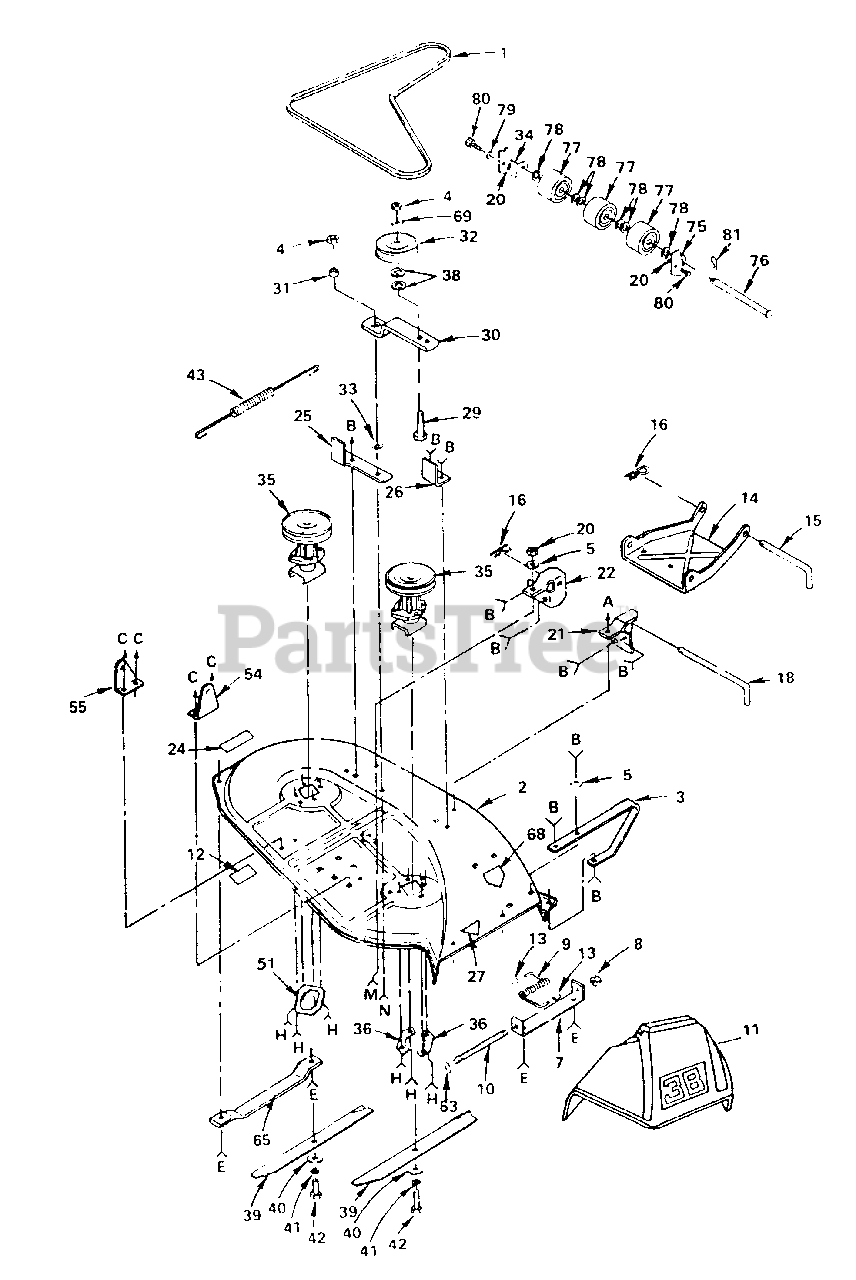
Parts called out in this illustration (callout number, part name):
2	Housing Assembly, Mower
3	Runner, R.H.
4	Nut, Lock, 3/8-16
5	Washer, 11/32 x 3/4 x 16 Ga.
6	Bolt, Carr., 5/16-18 x 5/8
7	Bracket, Deflector
9	Spring, Deflector
10	Rod, Hinge
11	Deflector, Shield
12	Decal, V-Belt Schematic
14	Link, Parallel
15	Pin, Hinge,Front
16	Spring, Retainer
18	Pin, Hinge, Rear
20	Nut, Lock 5/16-18
21	Bracket, Lift, R.H.
22	Bracket, Lift, L.H.
23	Bolt, Carriage 5/16-18 x 3/4
24	Decal, Instruction, Caution
25	Support, Arm
26	Stop, Deck, Front
27	Decal, Safety Standard serviced)
29	Bolt - 3/8-16 x 2 1/4
30	Arm, Idler
32	Pulley, Idler
33	Washer, Wear, 1/16
34	Bracket, Nose Roller, L.H.
35	Mandrel Assembly
36	Plate, Support, Mandrel
37	Screw - Hex Washer Hd. 3/8-16 x 1 1/4
38	Washer, 13/32 x 3/4 x 10 Ga.
39	Blade, 38"
40	Washer, 13/32 x 1-1/4 x 12 Ga.
41	Washer, Lock, 3/8
42	Bolt, Hex 3/8-24 x 1-1/2 Gr.5
43	Spring, Extension
50	Bolt, Carriage 3/8-16 x 3/4
51	Plate, Support
54	Bracket, Susp., Rear, R.H.
55	Bracket, Susp., Rear, L.H.
63	Washer, 11/32 x 5/8 x 16 Ga.
65	Runner, L.H.
67	Bolt, Carr. 3/8-16 x 1-1/4
68	Decal, Warning
69	Washer, 13/32 x 13/16 x 16 Ga.
75	Bracket, Nose Roller, R.H.
76	Pin, Pivot
77	Roller, Nose
78	Washer, 15/32 x 1 x 10 Ga.
79	Washer, 1/2 x 1 x 16 Ga.
80	Bolt, Hex 5/16-18 x 3/4
81	Cotter Pin, 1/8 x 3/4
